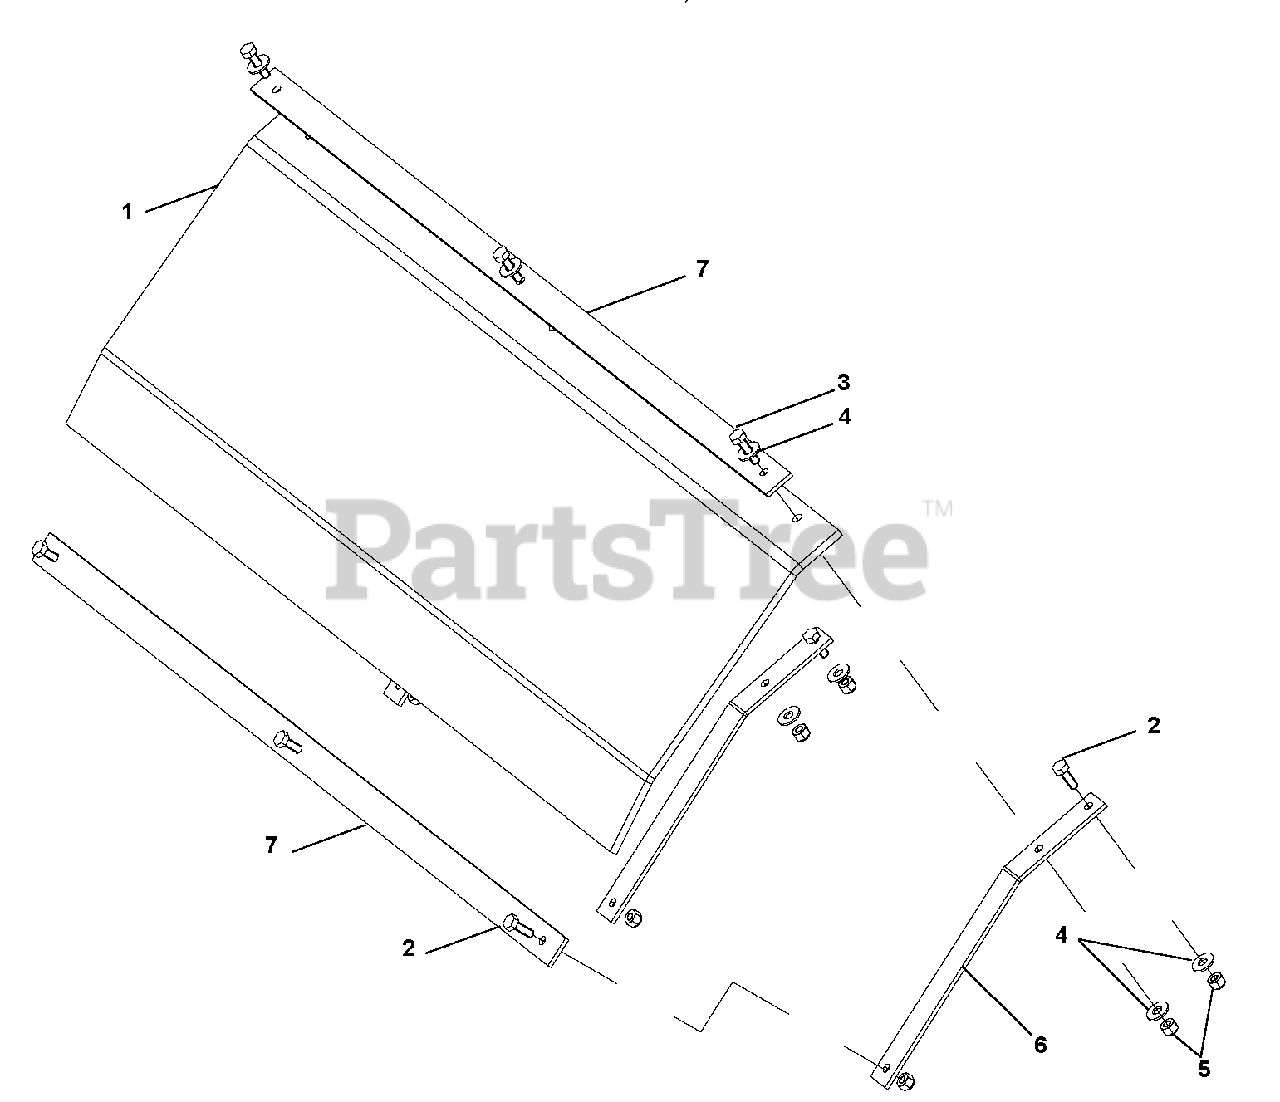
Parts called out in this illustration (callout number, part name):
1	DEFLECTOR, 3' MCD
2	@BLT-HEX .25-20X1.25 GR5 YWZC
3	@BLT-HEX .25-20X1.50 GR5 YWZC
4	@WSHR-FL-STL.312X.734X.065 YWZ
5	@NUT-LK-NYL .250-20 YWZC
6	STRAP, DEFLECTOR SUPPORT
7	STRAP, SUPPORT
